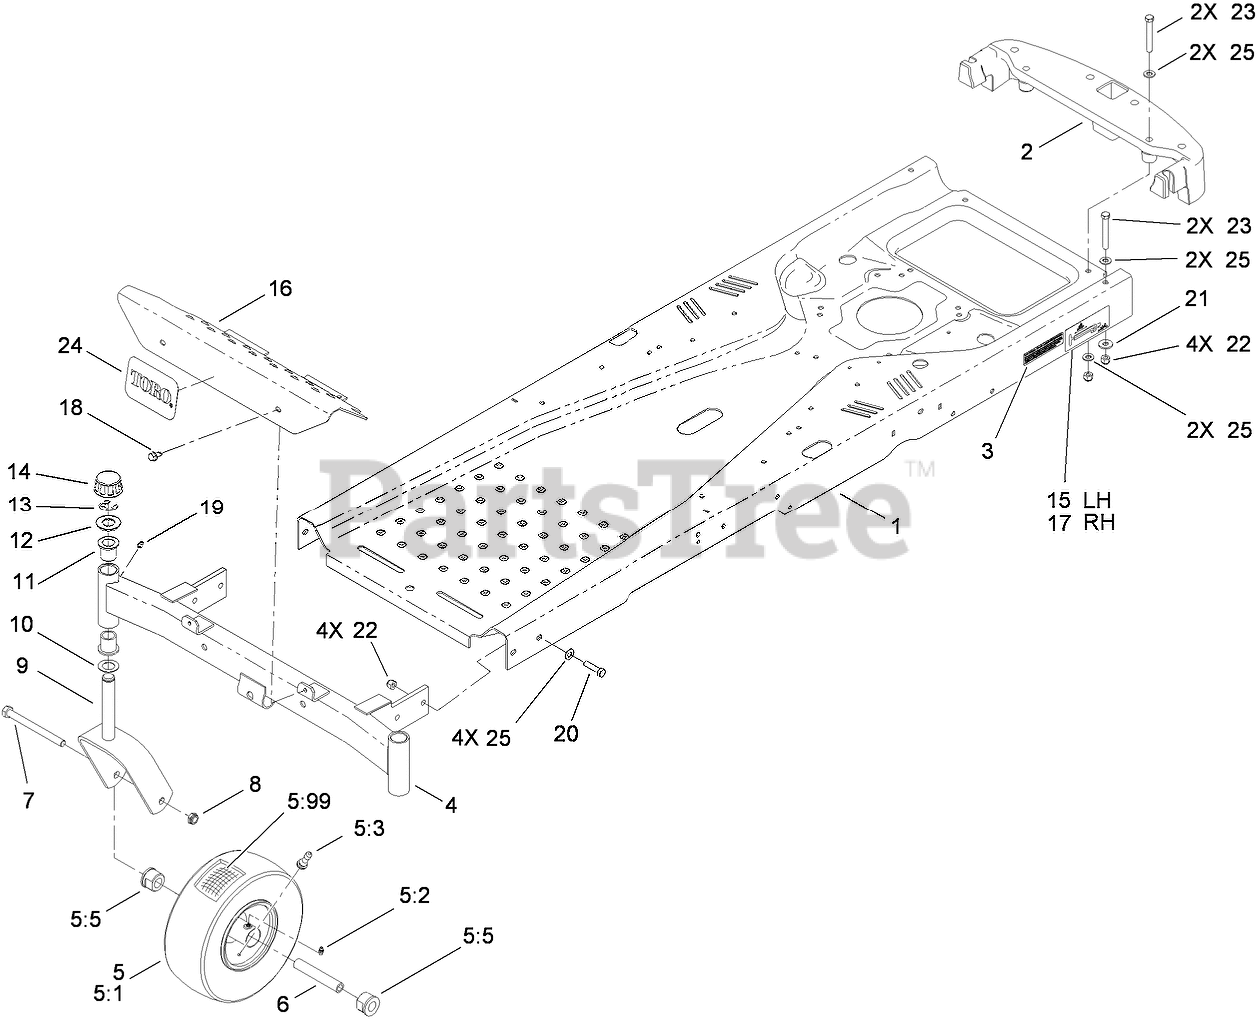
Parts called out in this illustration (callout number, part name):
2	BUMPER-REAR
3	DECAL-ARRESTER, SPARK
4	FRONT AXLE ASM
5	10 INCH TIRE AND WHEEL ASM
5:1	TIRE-RIBBED
5:2	FITTING-GREASE
5:3	STEM-VALVE
5:5	BUSHING-FLANGE
5:99	TUBE-INNER (W/VALVE)
6	BUSHING-SPANNER
7	SCREW-HH
8	NUT-LOCK, NI
9	CASTER FORK ASM
10	WASHER-THRUST
11	BEARING-FLANGED
12	WASHER
13	RING-RETAINING, EXT
14	CAP-HUB
15	DECAL-TRANSPORT, LH
16	FOOTREST
18	SCREW-HWH
19	FITTING-GREASE
20	SCREW-HH
21	WASHER-HARDENED
22	NUT-LOCK, NI
23	SCREW-HH
24	DECAL
25	WASHER-FLAT
